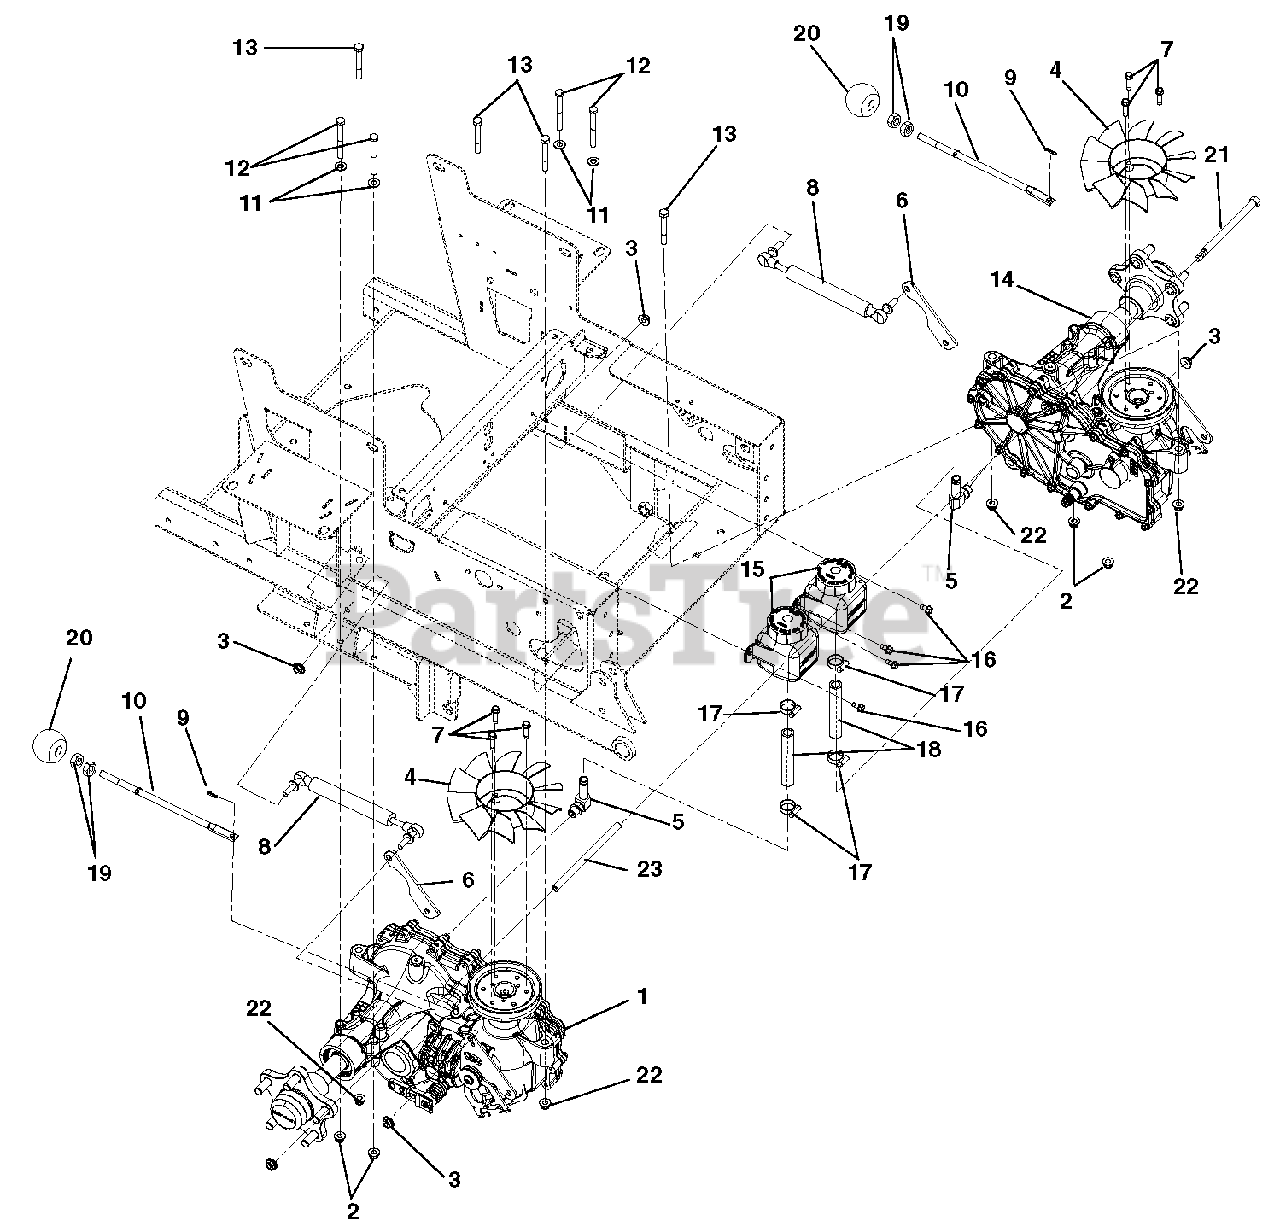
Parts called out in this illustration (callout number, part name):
1	Transaxle, 100I- Right Hand
2	Nut, .31-18 Nyloc Flange
3	Flange Patch M8-1.25
4	Fan, 2800 Series Cooling
5	Fitting, Hydraulic (90 DEG)
6	Plate, Control Reforcement
7	Screw, Tapping .25-20 x 1.00 Hex Washer Head Thread Rolling
9	Pin, Hair-Internal .06 x .18 x .77
10	Lever, 100I Dump Valve
11	Washer, Flat-Steel .344 x .688 x .065
12	Bolt, Hex .31-18 x 3.00 Grade 5
13	Bolt, Hex .38-16 x 2.50 Grade 5
14	Transaxle, 100I- Left Hand
15	Tank, Expansion ZT2800
16	Screw, Tapping .25-20 x .50 Hex Washer Head Thread
17	Clamp, .88 Diameter Hose
18	Hose, 100I Hydro Overflow
19	Nut, Jam .312-18 UNC YWZC
20	Knob, Ball Black .312-18 x 1.00
21	Bolt, Hex .38-16 x 11.00 Grade 5
22	Nut, Locking-Nylon-Flange .38-16
23	Spacer, .38 ID x 5/8 OD x 7.72
